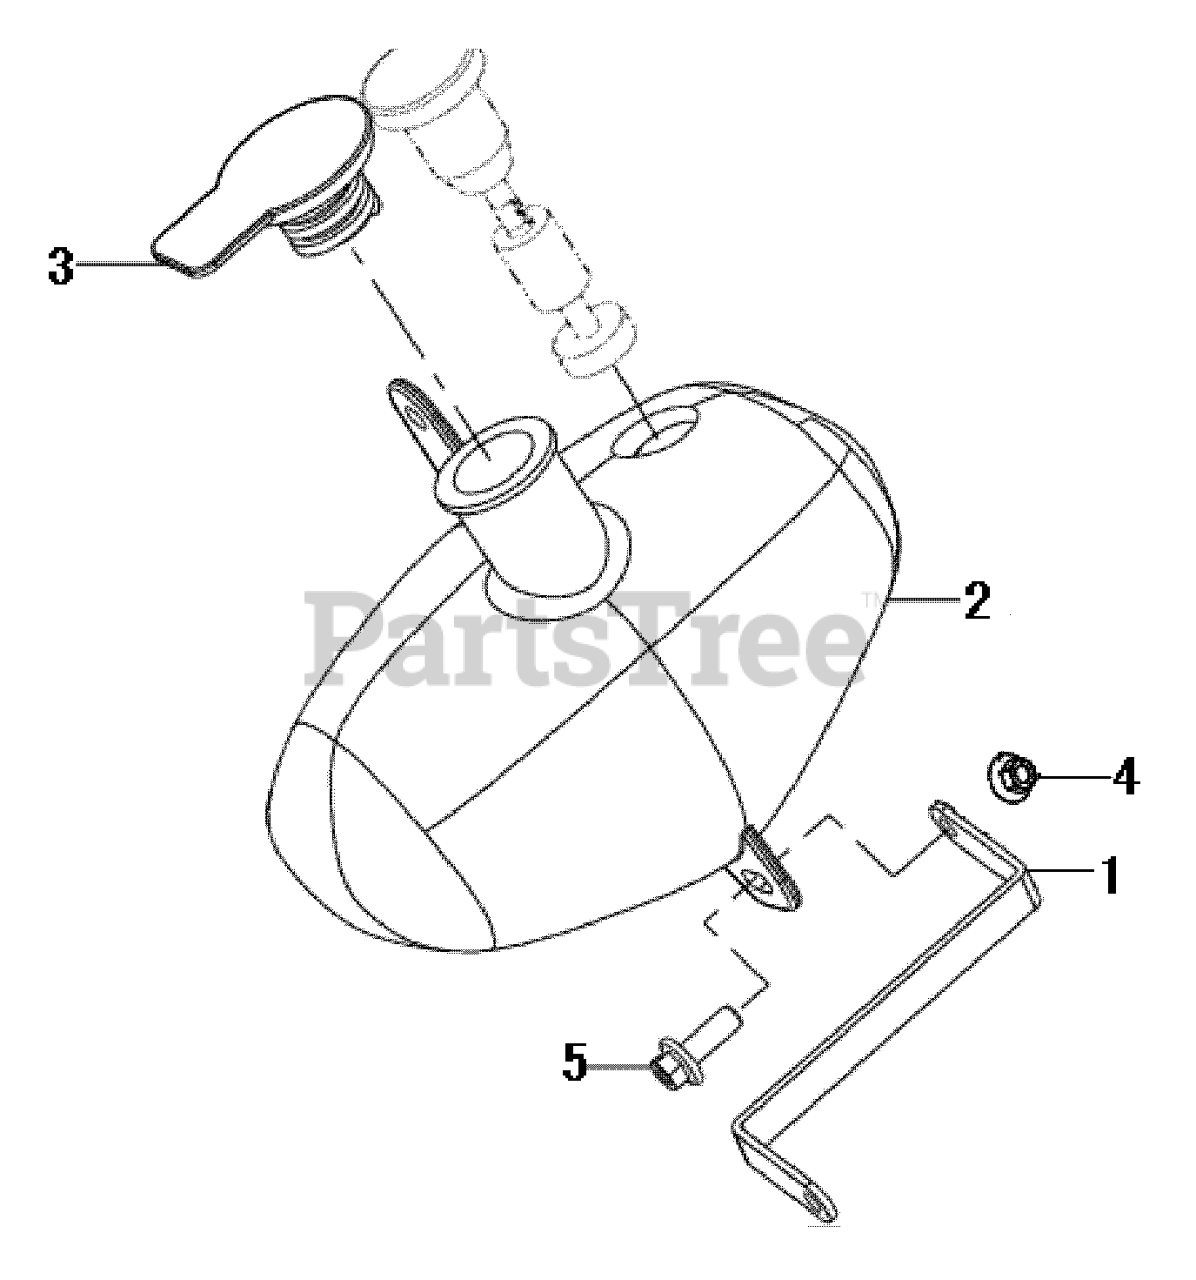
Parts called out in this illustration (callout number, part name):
1	BRACKET, OIL TANK MOUNTING
2	OIL TANK
3	CAP, OIL TANK
5	SCREW W/WASHER
